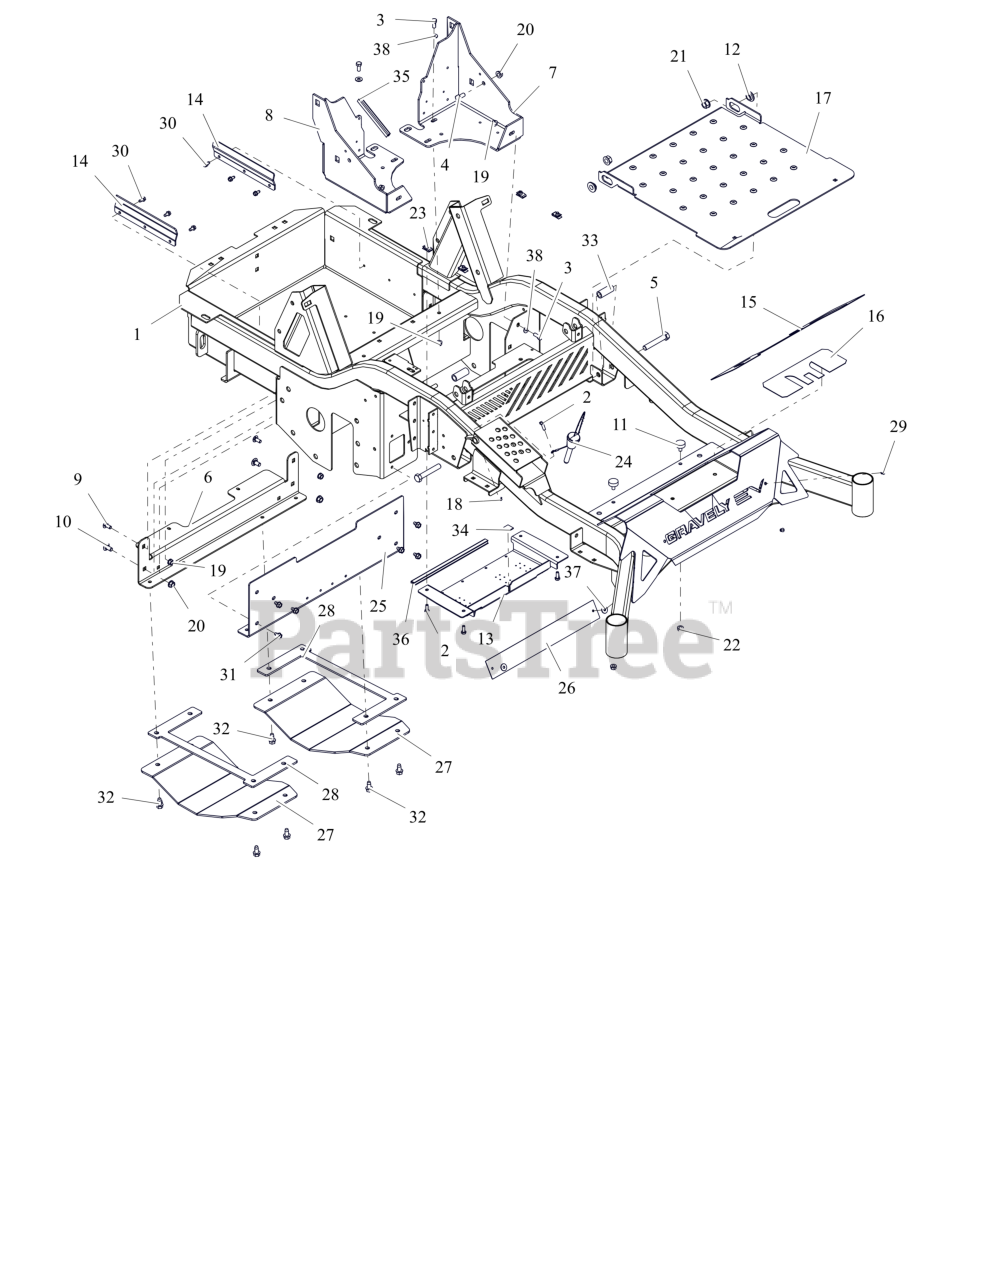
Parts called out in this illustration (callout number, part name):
1	KIT, EV FRAME W/DECALS-GRAVELY
2	BLT, HEX .25-20X.75 G5 ZCC
3	BLT,HEX .31-18X.75 G5 ZCC
4	BLT,HEX .38-16X.75 G5 ZCC
5	BLT, HEX .50-13X3.00 G5 ZCC
6	BRKT, SKID PLATE MTG. (RED)
7	BRKT, SUPPORT ROPS -LH (RED)
8	BRKT, SUPPORT ROPS-RH (RED)
9	BLT, RHSSN.31-18X.750 G5 ZCC
10	BLT, RHSSN .38-16X.75 G5 ZCC
11	BUMPER, RUBBER
12	BSHG-FLG .515X.750X.310X1.120
13	COVER, BOTTOM ACCESS -OPEN (RED)
14	DEFLECTOR, BATTERY -EV (RED)
15	GRIP, FRONT
16	GRIP, TAPE FRONT
17	KIT,ACCESS PANEL W/DECALS-RED
18	NUT-LK-CTR-FLG .25-20 ZC120
19	NUT,LK-CTR-FLG .31-18 GF ZCC
20	NUT-LK-CTR-FLG .375-16 GF ZCC
21	NUT-LK-CTR-FLG .500-13 GG ZCC
22	NUT,SPNLK-FLG .31-18 G5 ZCC
23	NUT-RTNR .25-20X.56
24	PIN, MAGNETIC .50X2.50
25	PLATE, FRONT FRAME (RED)
26	PLATE, BACK FOOT-REST XL
27	PLATE, SKID (BLACK)
28	PLATE, SKID TENSION (BLACK)
29	RIVET, .1875 AL/AL .126-.250
30	SCR-TAP .25-20X.50 HWH ZCC
31	SCR,TAP .312-18X.50 HWH TR ZCC
32	SCR,TAP .375-16X.75 HWH TR ZCC
33	SPACER, .515X.75X1.83
35	STRIP, COWL
36	STRIP, COWL
37	WSHR, RBR W/ADHESIVE .25X.75X.06
38	WSHR, FLT .312X.734X.065 ZCC
